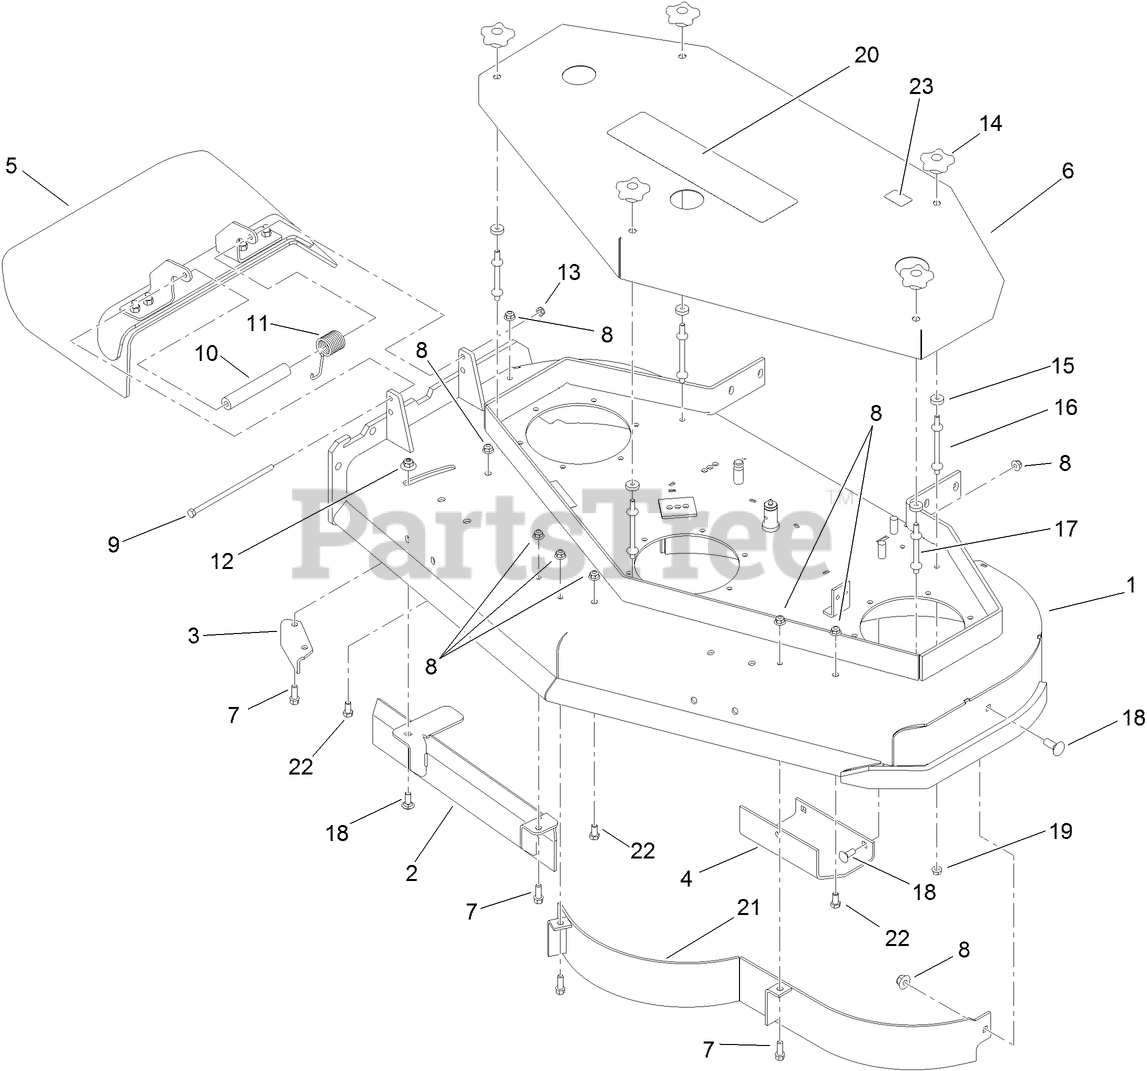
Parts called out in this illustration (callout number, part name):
1	DECK ASM
3	BAFFLE-DISCHARGE
5	DEFLECTOR ASM
7	SCREW-HWH
8	NUT-HF, NI
9	SCREW-HH
10	SPACER
11	SPRING-TORSION
12	NUT-FLANGE, NI
13	NUT-LOCK, NI
14	KNOB-HANDLE
15	WASHER
16	STUD-SHIELD, BELT (LONG)
17	STUD-SHIELD, BELT (SHORT)
18	BOLT-CARR
19	NUT-HF
22	SCREW-HH
23	DECAL-CAUTION
